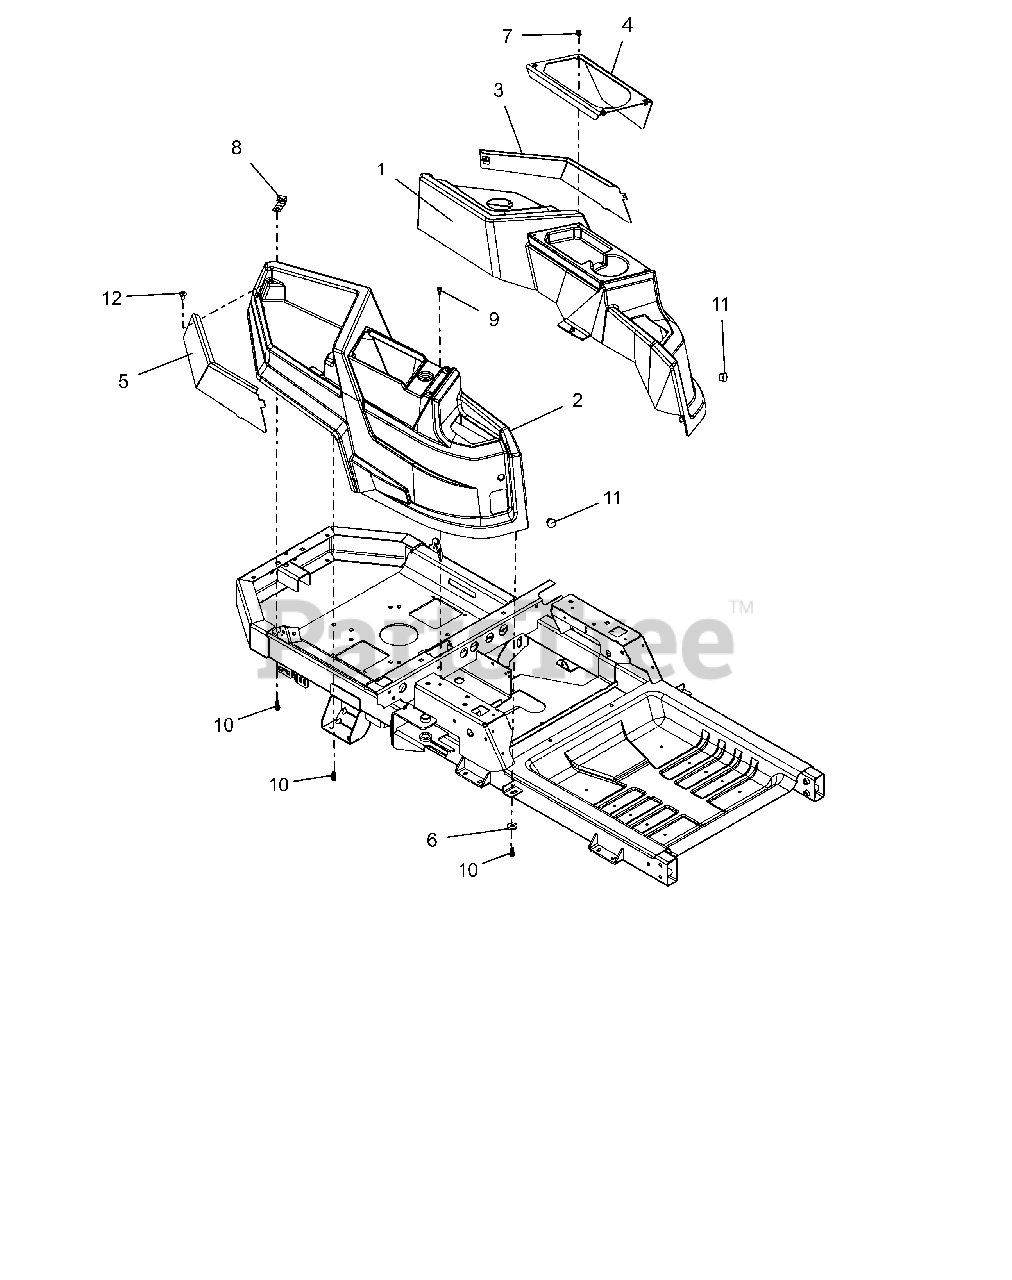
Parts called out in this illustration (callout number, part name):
1	FENDER, LH -ZOOM
2	FENDER, RH -ZOOM
3	WLDMT, FENDER BLOCKOFF XL -LH
4	PANEL, CUPHOLDER/STORAGE (LH)
5	WLDMT, FENDER BLOCKOFF-RH XL
6	WSHR-FL-STL .406X1.00X.188 YWZ
7	RIVET, PLASTIC .195 DIA.
9	SCR-TAP .25-20X.50 HWH TR YWZ
10	SCR-.312X.75 #14H H/W/H H/L CZ
11	PLUG, HOLE .75 (BLACK)
12	XMAS TREE FASTNER-BLACK
